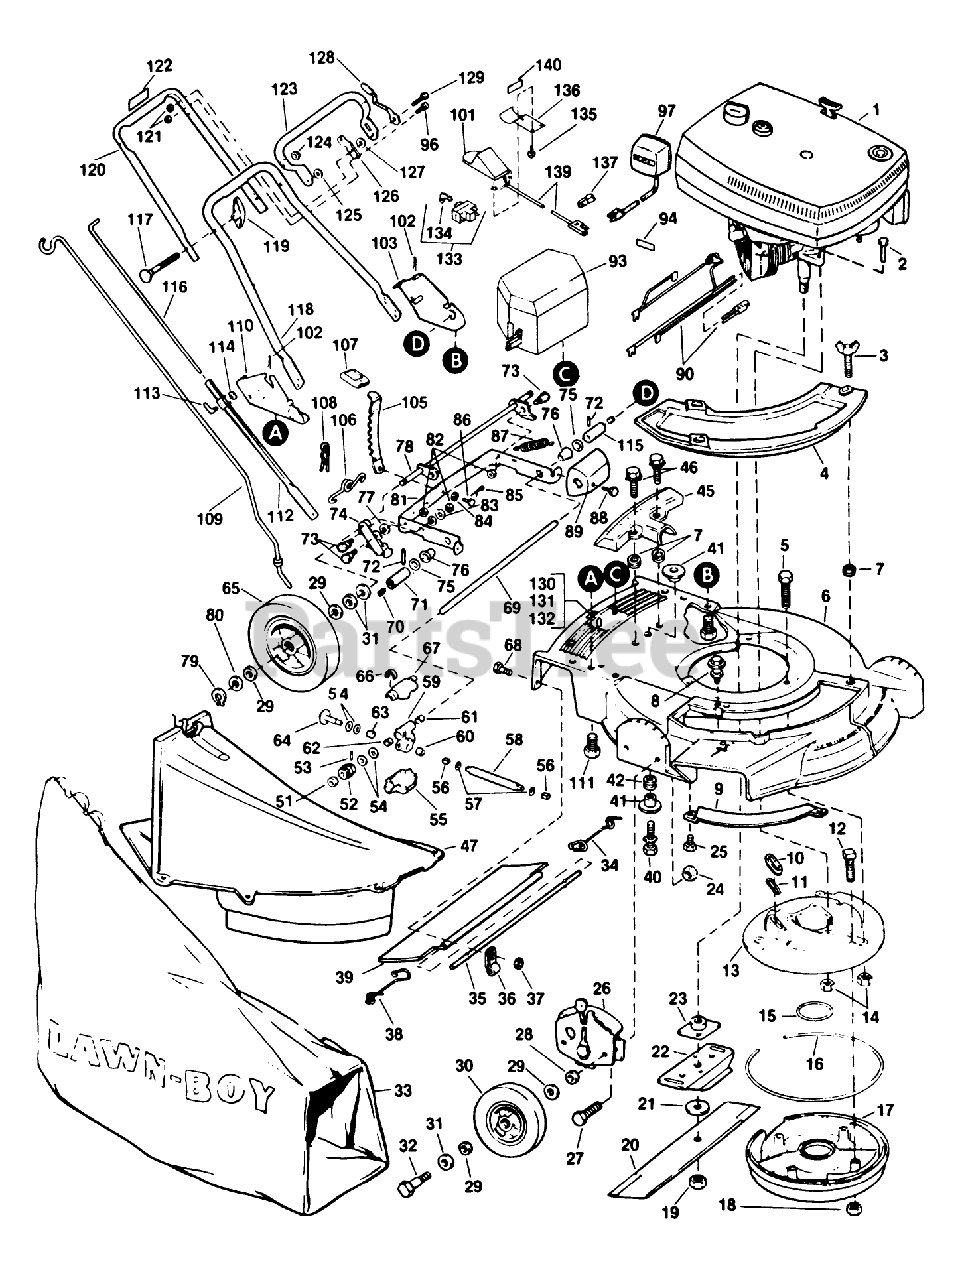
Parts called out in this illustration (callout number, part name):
1	See Note #2 at bottom of this page.
2	BOLT F
3	WING SCREW LAWRE
5	SCREW V
9	BAR-TOE
10	SLEEVE
11	GASKET S
12	SCREW
14	NUT-LOCK F
16	Gasket Muffler (outside)
18	LOCKNUT E
19	NUT-BLADE
21	WASHER
23	PLATE AND COLLAR ASM
24	NUT-LOCK F
28	WASHER WROUGHT
29	WASHER
30	WHEEL & TIRE KIT
31	SPACER
32	BOLT WHEEL
33	ORD LB 89802 WHOLE GOODS
34	SPRIG T/SHLD ASOC
35	ROD 21" ADVANCE
36	CLAMP ROD KMC
37	LOCKNUT E
38	SPRING;TRAILING SHIELD RH
41	SPACER ECK PRES
42	GROMMET
45	COVER
46	SCREW SEMS TRM HEX HD
47	Chute Assembly
51	WASHER
53	ROLL PIN
54	THRUST WASHER
56	BUSHING
57	O Ring
63	NEEDLE BEARING
67	GEAR COVER UPPER
69	DRIVE SHFT TAG AY
70	Plug
72	PIN
73	BOLT RB&W
77	WASHER S
79	RET RING
80	SPACER
82	STOP NUT
84	WASHER SPRING LAR
86	PIN
87	SPRING
89	GUARD
102	HAIR PIN
105	LEVER
106	SPRING N.A.S
107	KNOB
109	ROD GRASSBAG
111	SCREW
116	ROD CONTROL
119	NUT-WING
120	HANDLE
121	LOCKNUT E
125	WASHER M
128	KNOB & SPRING
129	BOLT RB&W
132	Nut
